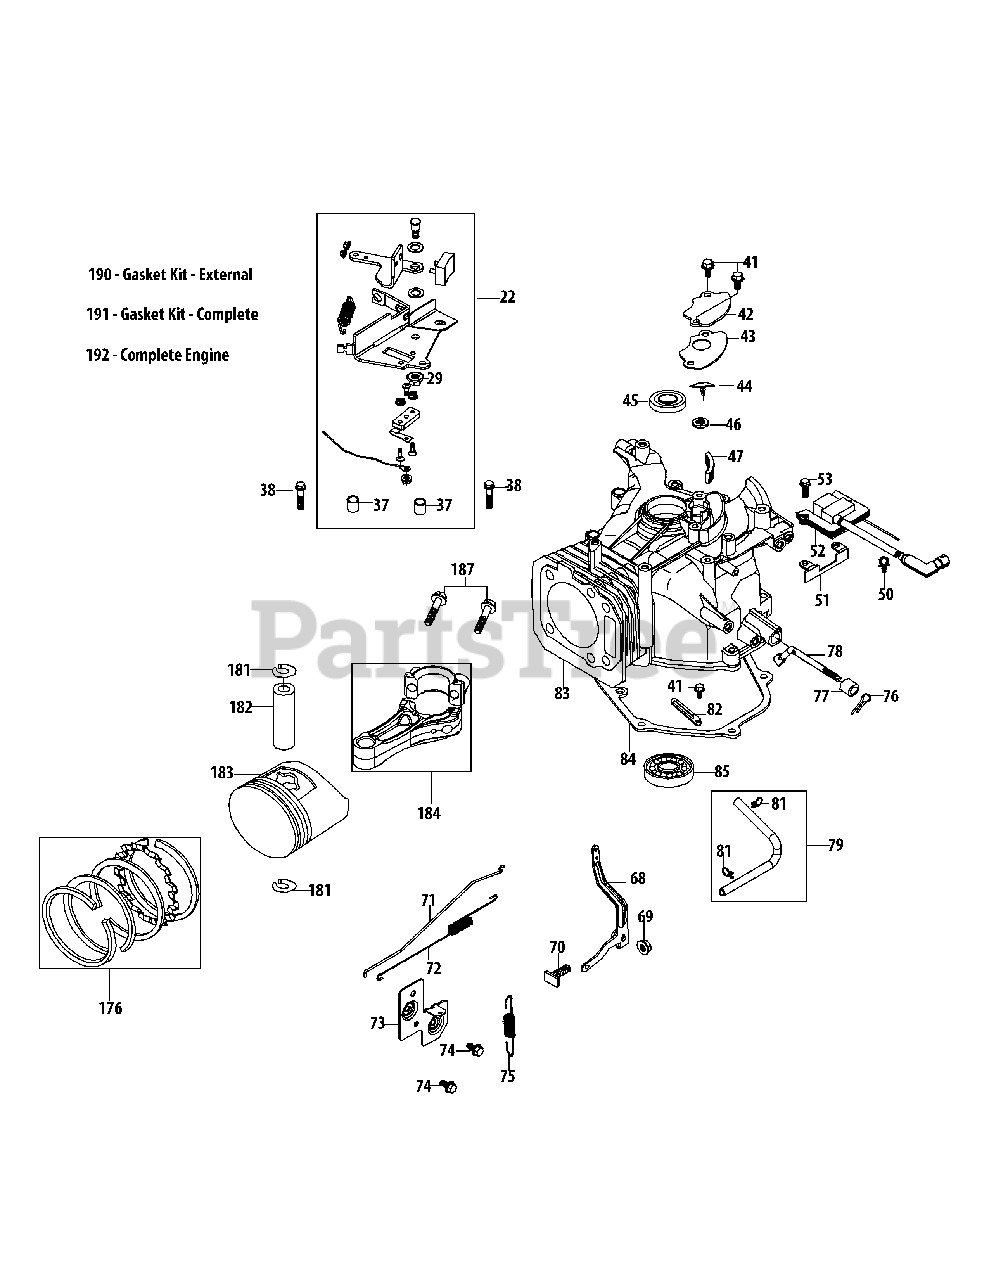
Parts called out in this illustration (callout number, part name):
22	Stop Switch and Brake Ass'y
29	Brake Arm Nut
37	Brake Spacer
38	Bolt M6X35
41	Bolt M6X14 Multi-Purpose
42	Breather Cover Plate
43	Breather Gasket
44	Breather Valve
45	Upper Crankshaft Seal
46	Breather Valve Base
47	Breather Screen
50	Ignition Wire Clip
51	Ignition Coil Bracket
52	Ignition Coil Assembly
53	Bolt M6X18
68	Governor Arm
69	Governor Arm Nut M6
70	Governor Arm Bolt
71	Throttle Linkage
72	Throttle Linkage Spring
73	Component Bracket
74	Bolt M6X12
75	Governor Spring
76	Governor Arm Shaft Cotter Pin
77	Governor Seal
78	Governor Arm Shaft
79	Breather Hose Assembly
81	Breather Hose Clamp
82	Flexible Clamp
83	Shortblock
84	Crankcase Cover Gasket
85	Main Bearing
176	Piston Ring Set
181	Piston Pin Snap Ring
182	Piston Pin
184	Connecting Rod Assembly
187	Connecting Rod Bolt
190	Gasket Kit - External
191	Gasket Kit - Complete
192	Complete Engine
